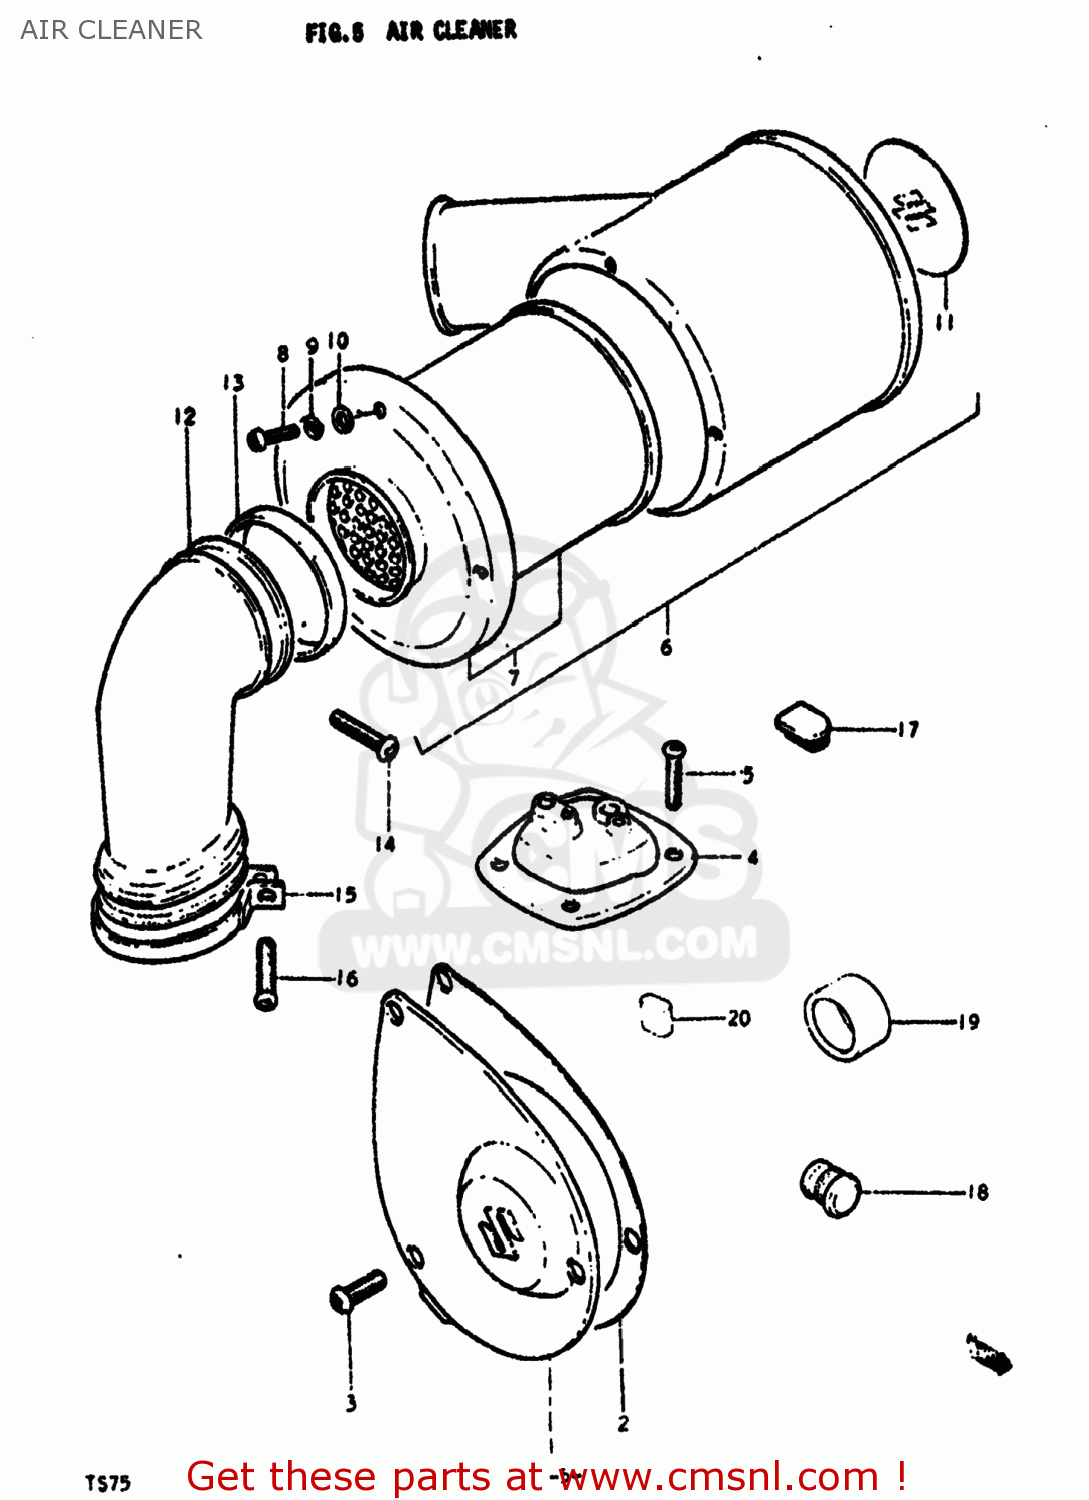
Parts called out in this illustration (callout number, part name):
1	CAP,CARBURETOR INSPECTION
2	GASKET,CARBURETOR INSPECTION (MCA)
3	SCREW
4	COVER,CARBURETOR TOP
5	SCREW
6	CLEANER ASSEMBLY,AIR
7	FILTER ASSY
8	SCREW
9	LOCK WASHER
10	WASHER
11	EMBLEM
12	TUBE,AIR CLEANER OUTLET
13	CLAMP
14	SCREW TAPP.
15	CLAMP
16	SCREW
17	CAP
18	Plug
19	GASKET,CARBURETOR INSULATOR (NAS)
20	CUSHION
